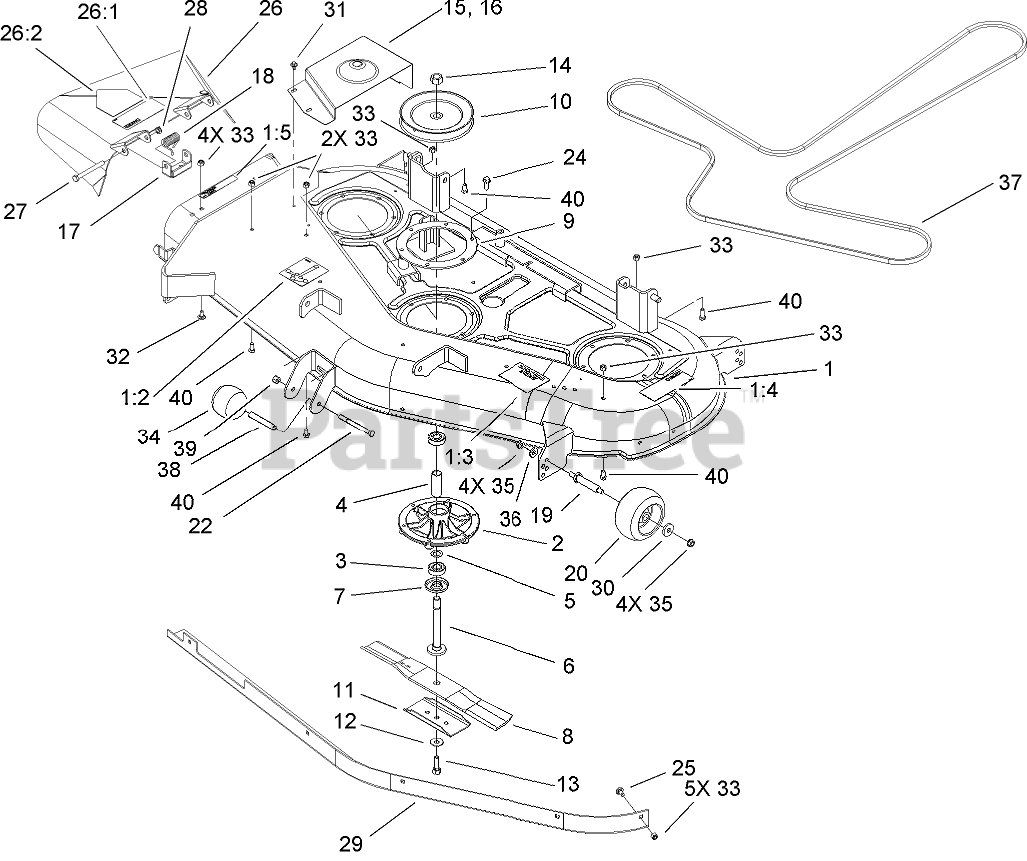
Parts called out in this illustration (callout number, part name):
1	DECK ASM
1:2	DECAL-ROUTING, BELT
1:3	DECAL-WHEEL, GAGE
1:4	DECAL-DANGER
1:5	DECAL-CAUTION
2	HOUSING-SPINDLE
3	BEARING-BALL
4	SPACER
5	SPACER
6	SHAFT-SPINDLE
7	SHIELD-BEARING
9	RING-SUPPORT, DECK
10	PULLEY AND HUB ASM
11	STIFFENER-BLADE
12	WASHER-BELLEVILLE
13	SCREW-HH
14	NUT-HEX
15	COVER-BELT, LH
16	COVER-BELT, RH
17	BRACKET-PIVOT
18	SPRING
19	SPACER
20	WHEEL-GAGE
22	SCREW-HH
24	SCREW-TAPTITE
25	SCREW-CARR
26	Deflector ASM
26:1	DECAL-DANGER
26:2	DECAL-DANGER
27	SCREW-HH
28	NUT-HEX
30	WASHER
31	SCREW-HHFTF
32	SCREW-CARR
33	NUT-LOCK, NI
34	ROLLER
35	NUT-HHF, WHIZ
36	WASHER-BELLEVILLE
37	BELT-V
38	TUBE-SPACER, WHEEL
39	NUT-LOCK, NI
40	SCREW-HH
